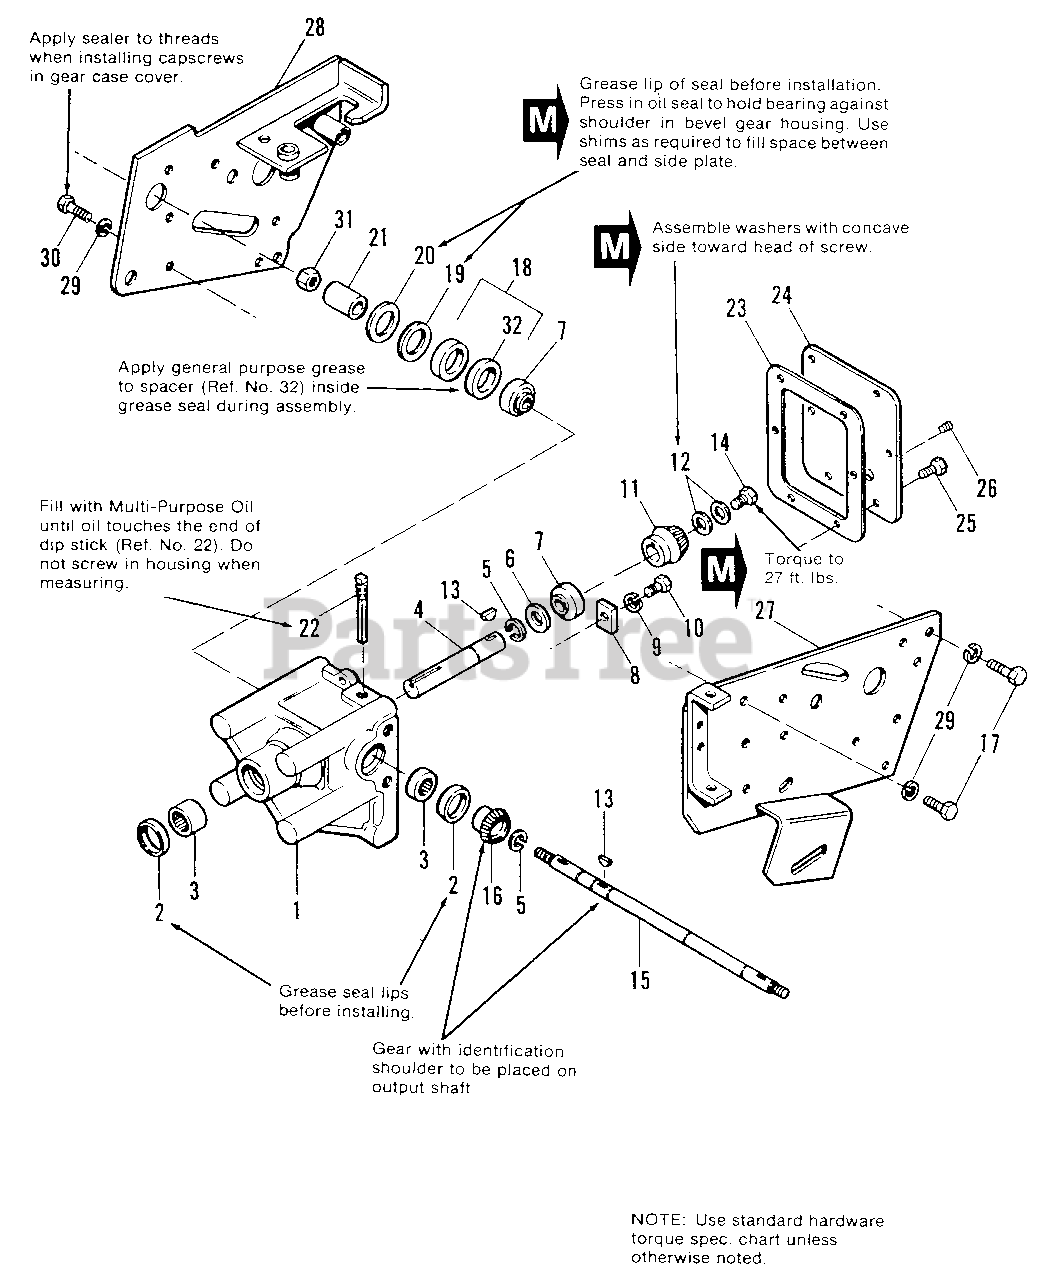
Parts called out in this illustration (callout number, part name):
1	HOUSING, Bevel Gear
3	BEARING, Needle
4	SHAFT, Driver
5	RING, Retaining
7	BEARING, Ball
8	PLATE, Bearing Clamp
9	LOCKWASHER, 5/16
10	CAPSCREW, Hex Hd., 5/16-18 x 5/8
11	GEAR, Bevel Driver
13	KEY, Woodruff #9
14	CAPSCREW, Hex Hd., 5/16-18 x 3/4
15	SHAFT, Driven
16	GEAR, Bevel Driven
17	CAPSCREW. Hex Hd., 7/16-14 x 1-1/4
18	SEAL, Oil Kit
25	CAPSCREW, Hex, 1/4-20 x 5/8
27	PLATE ASSY., Side, L.H.
28	PLATE ASSY., Side, R.H.
29	LOCKWASHER, 7/16
30	CAPSCREW, Hex Hd., 7/16-14 x 1
31	LOCKNUT, Hex, Jam, 3/4-16
32	SPACER, Oil Seal
